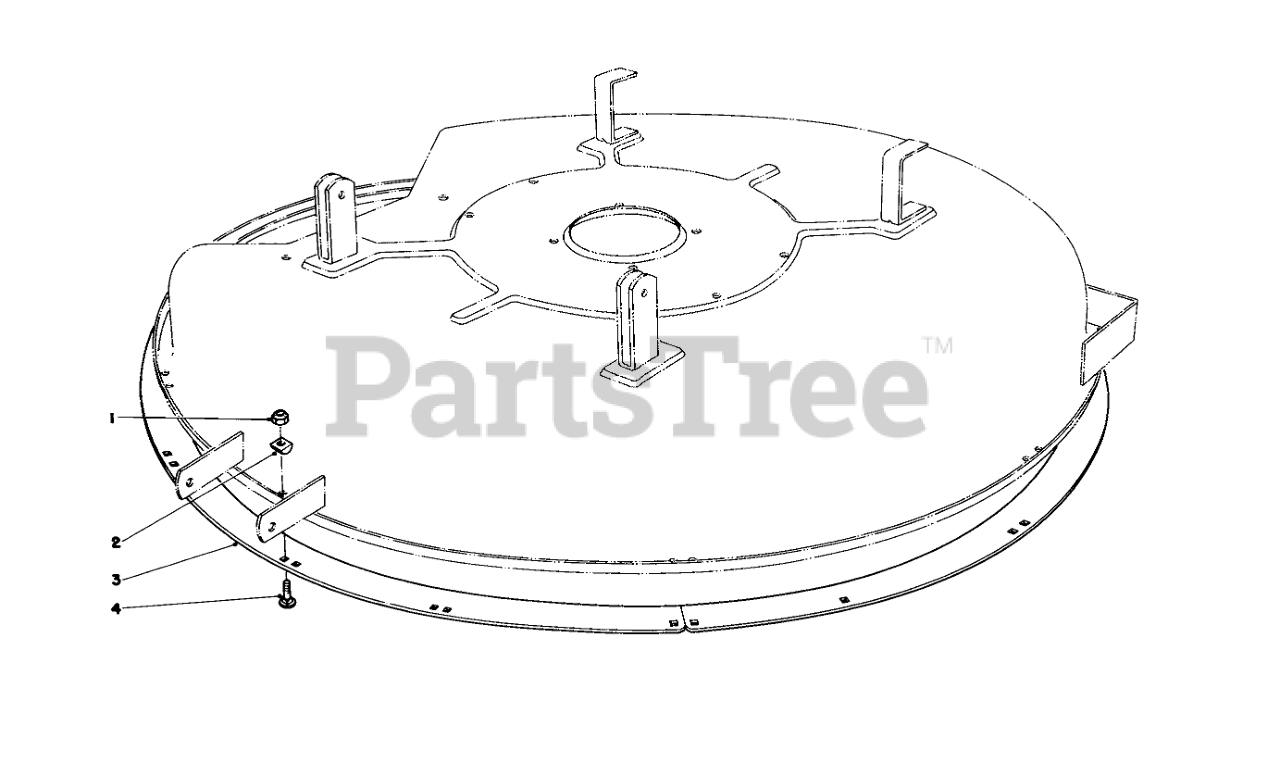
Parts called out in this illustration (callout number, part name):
1	NUT-LOCK, NI
2	Spacer-Deck Ring
3	DECK RING B
4	BOLT-CARR
